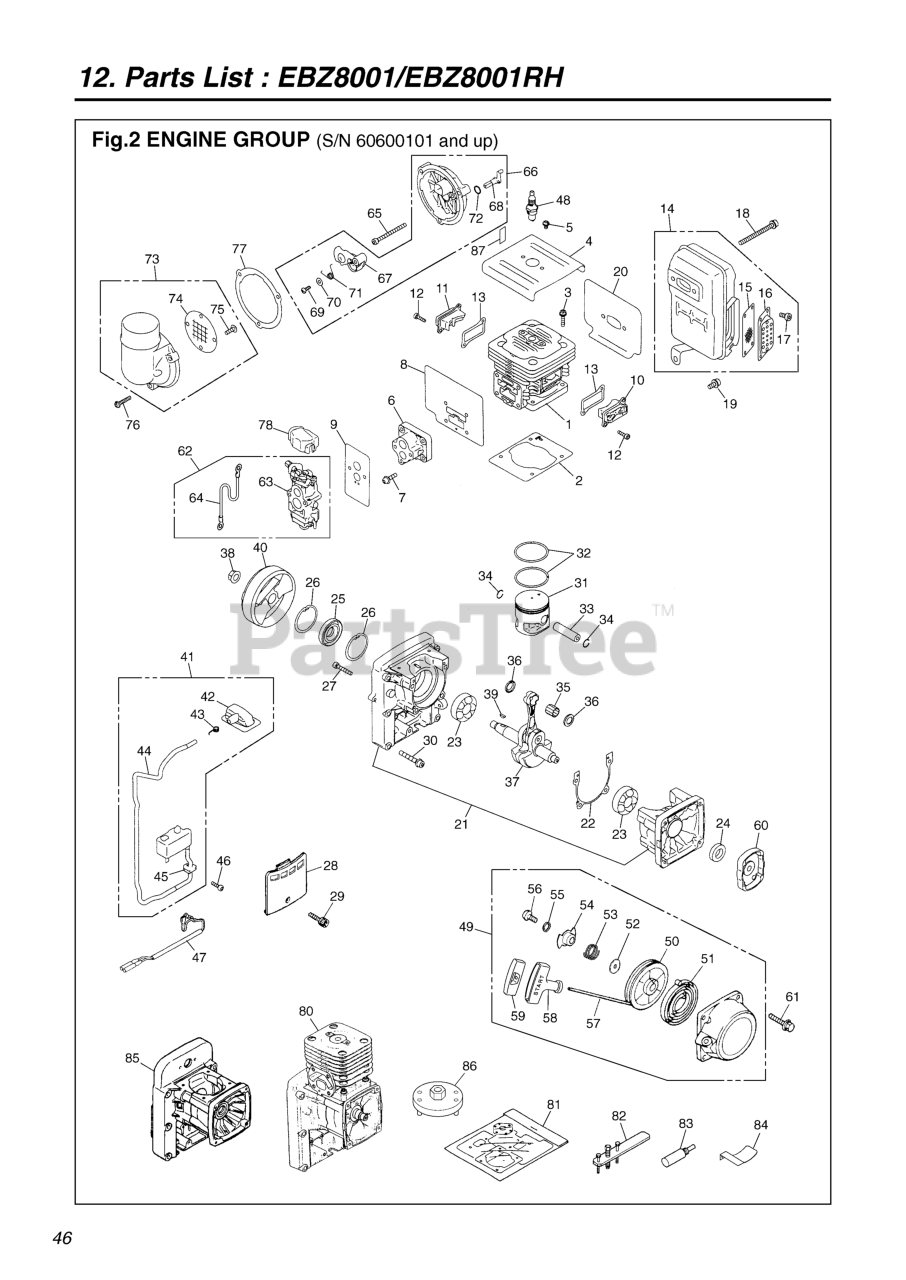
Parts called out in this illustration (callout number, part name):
1	CYLINDER (EBZ8000)
2	GASKET, BASE
3	BOLT
4	PLATE, CYL
5	SCREW TORX
6	INSULATOR
7	BOLT TORX
8	GASKET, INSULATOR
9	GASKET, CARB.
10	COVER, TR-S
11	COVER,TR-F
12	BOLT TORX
13	GASKET, TR
14	Muffler Assy
15	Arrester
16	Diffuser
17	Bolt
18	BOLT TORX
19	BOLT
20	GASKET, MUFFLER (RPLS. -15C0)
21	CRANKCASE-CASE
22	GASKET, CASE
23	BEARING
24	SEAL
25	SEAL
26	SNAP RING
27	BOLT
28	COVER
29	BOLT TORX
30	BOLT TORX
31	PISTON
32	RING
33	PIN
34	SNAP RING
35	BEARING
36	WASHER
37	CRANKSHAFT-C
38	NUT, M10
39	KEY
40	ROTOR
41	COIL ASSY
42	CAP
43	SPRING
44	TUBE
45	GROMMET
46	BOLT TORX
47	CORD-C
48	SPARK PLUG
49	RECOIL ASSY (RPLS -7511)
50	REEL (REPLACES -75C1)
51	SPRING
52	WASHER (REPLACES -75M0)
53	SPRING, FRICTION (RPLS. -75L1)
54	PLATE, FRICTION (RPLS. -75K1)
55	WASHER (REPLACES -75W0)
56	SCREW
57	ROPE
58	KNOB
59	COVER KNOB
60	PULLEY (RPLS 848-H00-7520)
61	BOLT, TORX
62	CARBURETOR SET
63	CARBURETOR-A (WYA-44)
64	Cord
65	BOLT
66	CUP ASSY
67	PLATE, CHOKE
68	LEVER
69	SCREW
70	WASHER
71	SPRING
72	O-RING
73	COVER ASSY. (REPLACES -8340)
74	SCREEN
75	SCREW
76	SCREW
77	GASKET,CUP
78	COVER
80	SHORT BLOCK (EBZ8000)
81	GASKET KIT
82	PULLER ASSY
83	STOPPER (TOOL)
85	CRANKCASE-A
86	PULLER
87	LABEL, CHOKE
